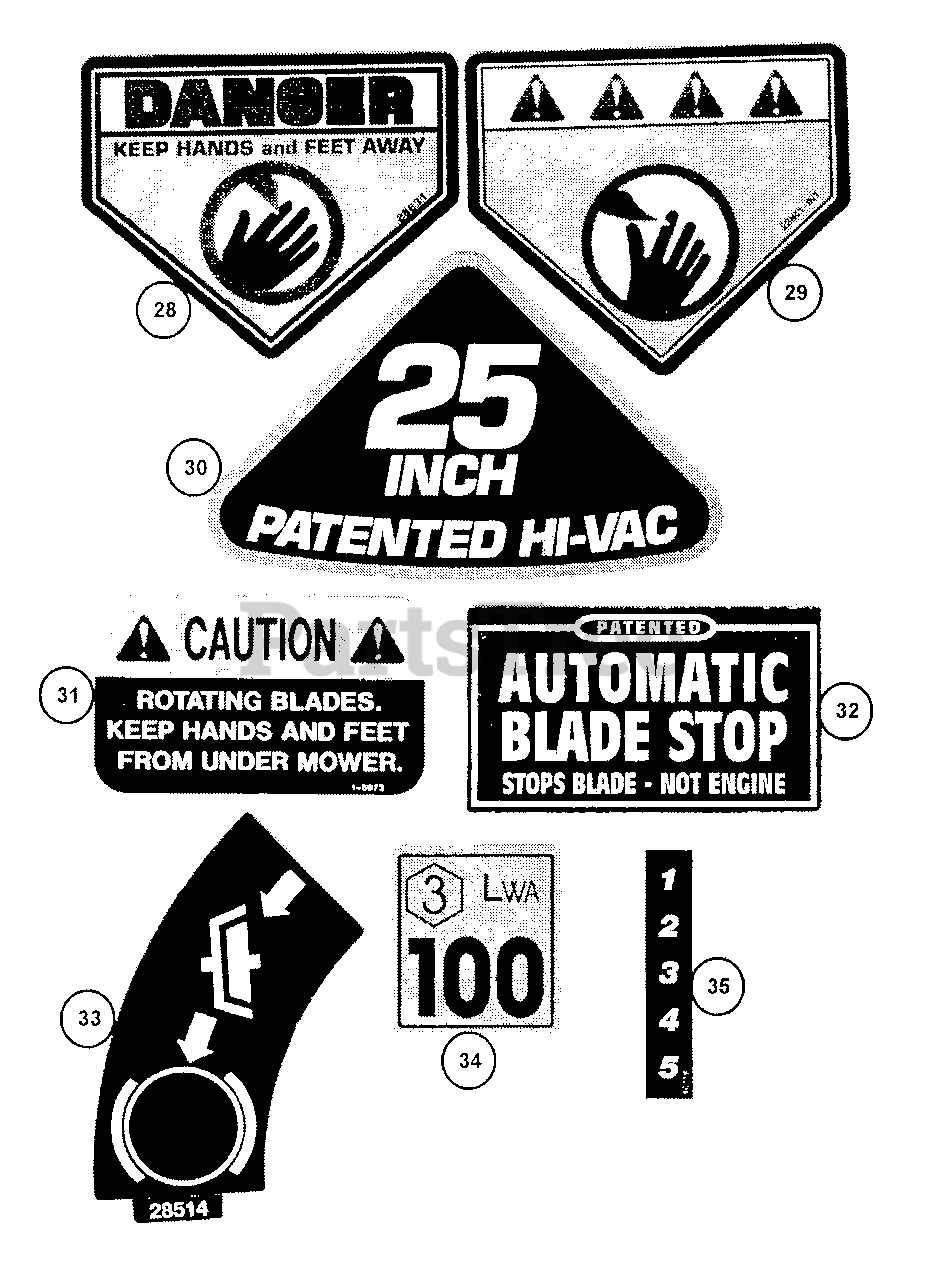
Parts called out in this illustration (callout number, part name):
28	DECAL, Danger
29	DECAL, Danger (International)
30	DECAL, 25" Patented Hi-Vac
31	DECAL, Caution (Rotating Blades)
32	DECAL, ABS Pedal
33	DECAL, Clutch/Brake (Symbol)
34	DECAL, Noise
35	DECAL, Height of Cut
